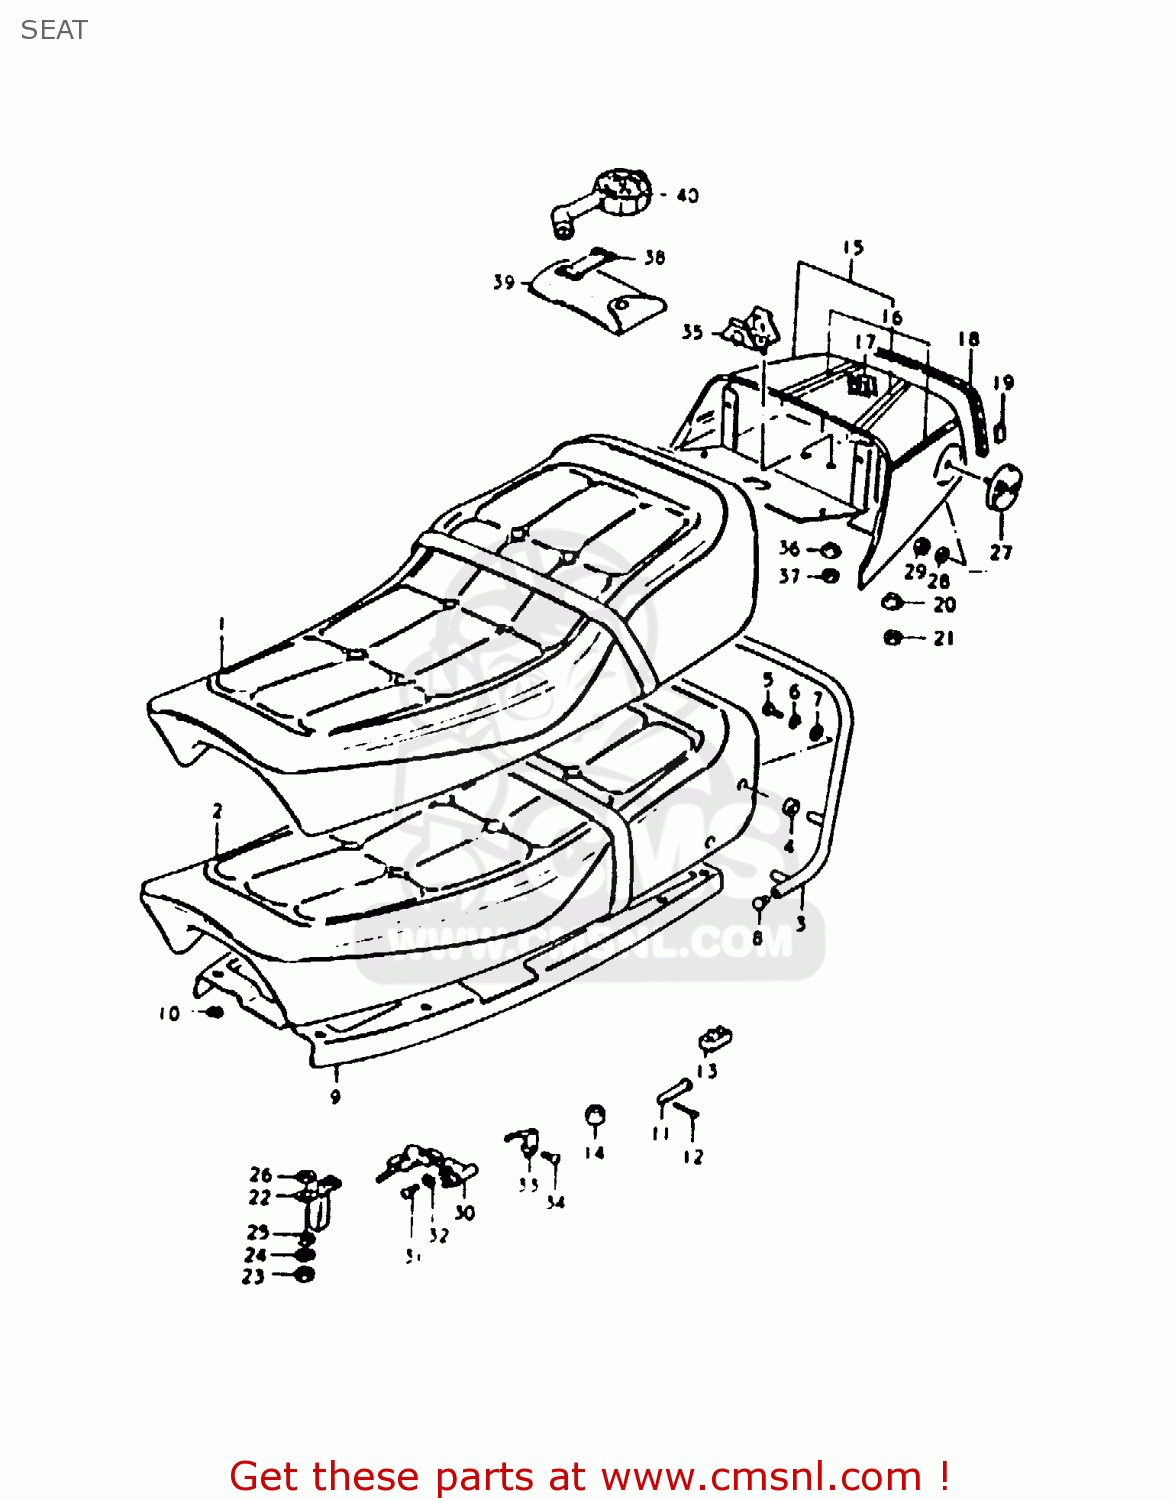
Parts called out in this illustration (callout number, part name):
1	SEAT ASSEMBLY
2	SEAT ASSEMBLY
3	HANDLE,PILLION RIDER
4	CUSHION
5	BOLT
6	LOCK WASHER
7	WASHER
8	END,SHEET HANDLE
9	MOLDING,SEAT
10	NUT
11	PIN
12	PIN
13	CUSHION
14	CUSHION
15	COVER SET,SEAT TAIL
16	TAPE SET
17	EMBLEM,SEAT TAIL COVER
18	GROMMET
19	CLIP,SEAT TAIL COVER M
20	WASHER
21	NUT 6MM
22	STRIKER,SEAT LOCK
23	NUT
24	LOCK WASHER
25	WASHER
26	WASHER (6.5X20X1.2)
27	REFLEX REFLECTOR,RR
28	WASHER
29	NUT
30	LOCK ASSY,SEAT
31	SCREW
32	LOCK WASHER
33	SPRING,HELMET HOLDER
34	SCREW
35	HOLDER,TOOL
36	WASHER
37	NUT
38	BAND
39	TOOL SET
40	GAUGE ASSEMBLY,AIR PRESSURE
